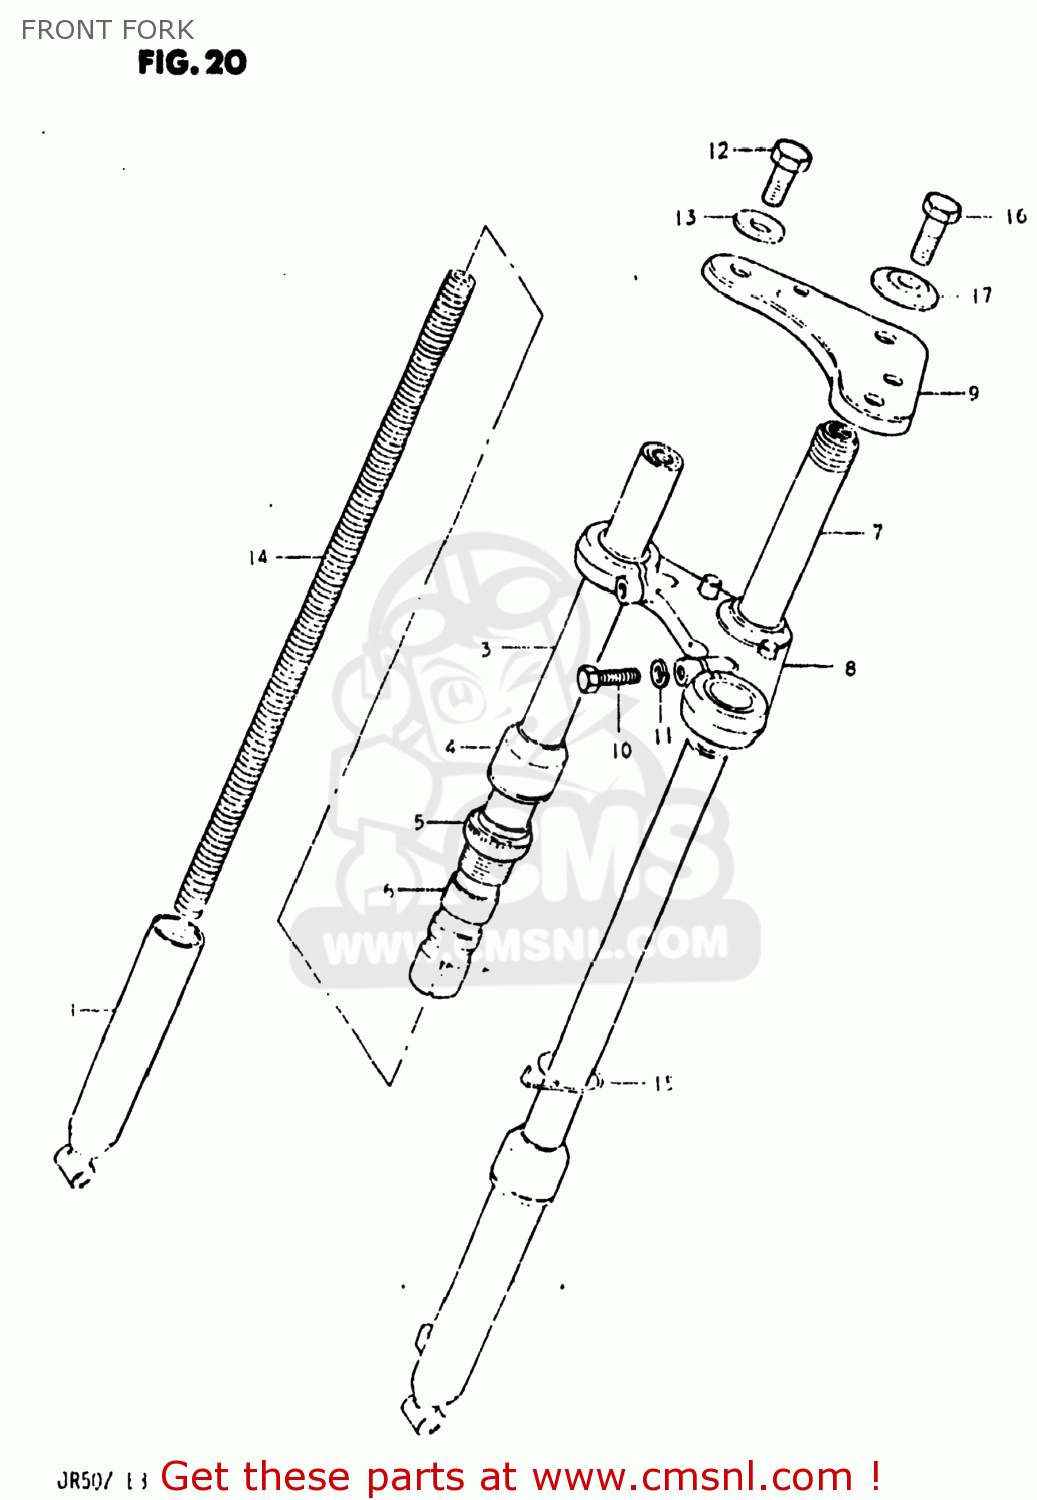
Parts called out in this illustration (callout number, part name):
1	TUBE,OUTER,RIGHT
2	TUBE,OUTER,LEFT
3	TUBE,FORK,INNER
4	SEAL,DUST
5	NUT,OUTER
6	STOPPER
7	STEM,STEERING
8	RACE,STEERING,OUTER,LOWER
9	HEAD,STEERING STEM
10	BOLT
11	LOCK WASHER
12	BOLT,FRONT FORK,UPPER
13	WASHER,STEERING STEM HEAD
14	SPRING
15	CLIP
16	CAP,FORK INNER TUBE
17	WASHER
